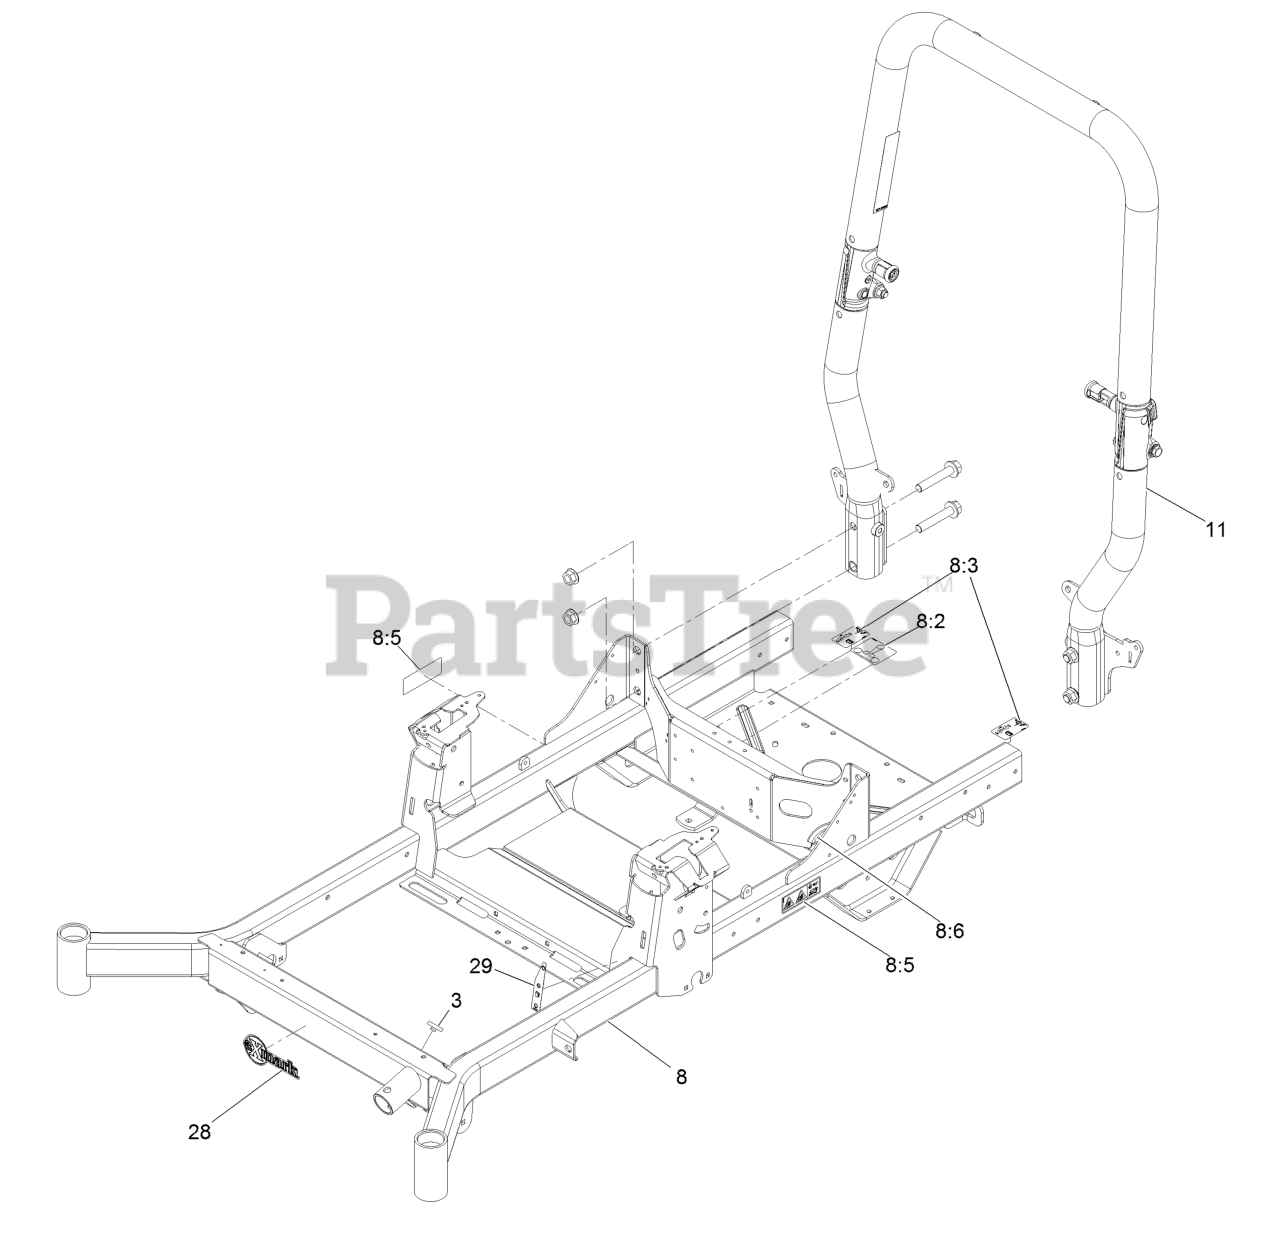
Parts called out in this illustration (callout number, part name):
3	Bumper-Push-In, Rubber
8	Frame-60, Suspension
8:2	Decal-Routing, Belt
8:3	Decal-Release, Drive
8:5	Decal-Warning
8:6	Strip-Seal
11	ASM-ROPS Tapered
28	Decal-Exmark Logo
29	Decal-Fill, Fuel
